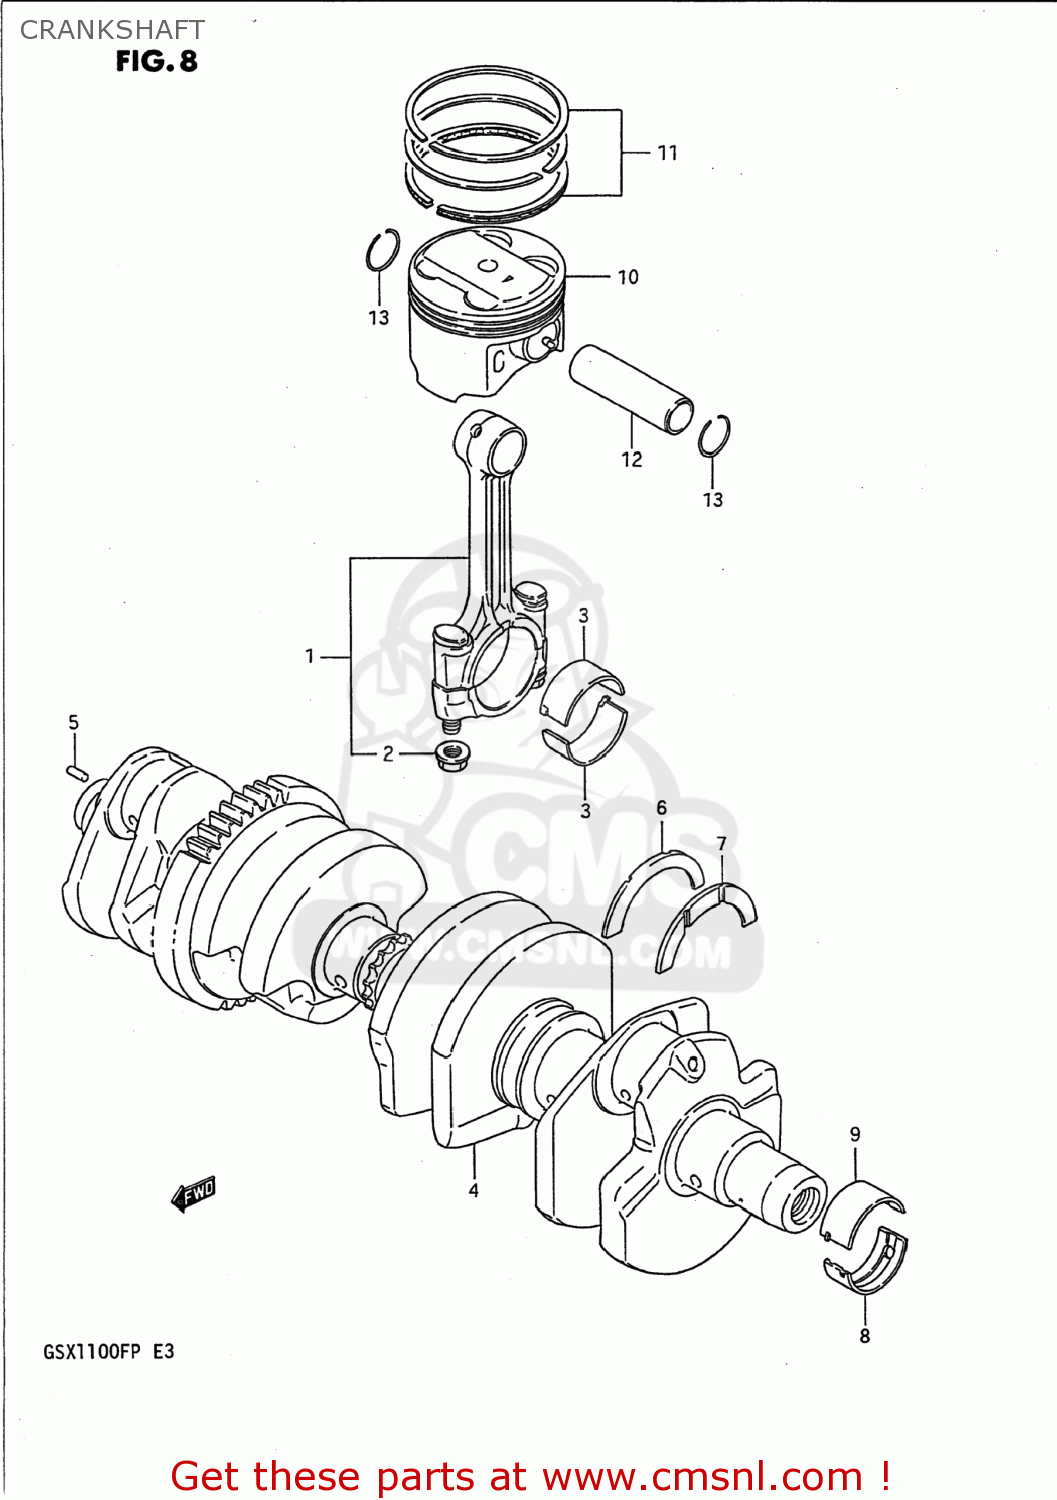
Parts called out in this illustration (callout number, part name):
1	ROD ASSY,CONNECTING
2	NUT
3	BEARING,CRANK PIN
4	CRANKSHAFT SET
5	PIN
6	BEARING,CRANK THRUST(GREEN)
7	BEARING,CRANK THRUST(RED)
8	BEARING,CRANKSHAFT LWR
9	BEARING,CRANKSHAFT UPR
10	PISTON
11	RING SET,PISTON
12	PIN,PISTON
13	CIRCLIP,PISTON PIN
